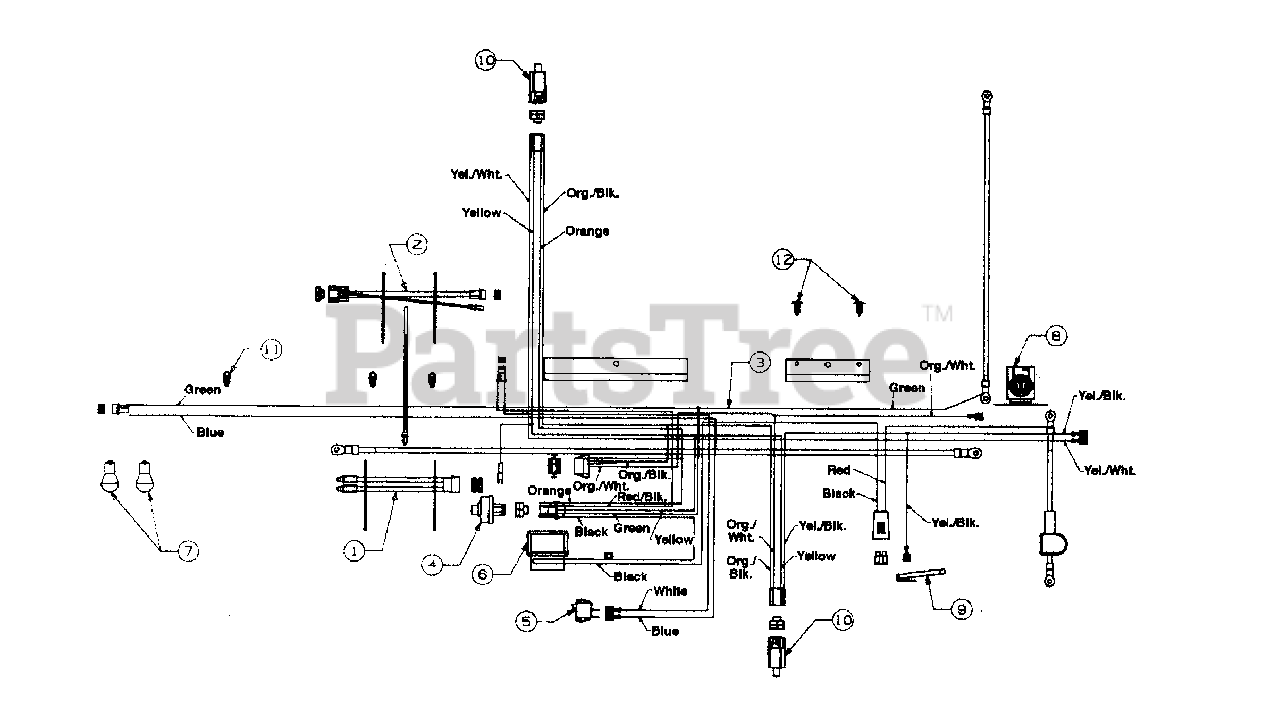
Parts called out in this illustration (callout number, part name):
1	Ratchet
2	Safety Switch
3	Solenoid
4	Bulb (Headlight)
5	Ammeter
6	Light Switch
7	Ignition Switch
9	Wire Harness Adapter
10	Wire Harness (Monitor)
